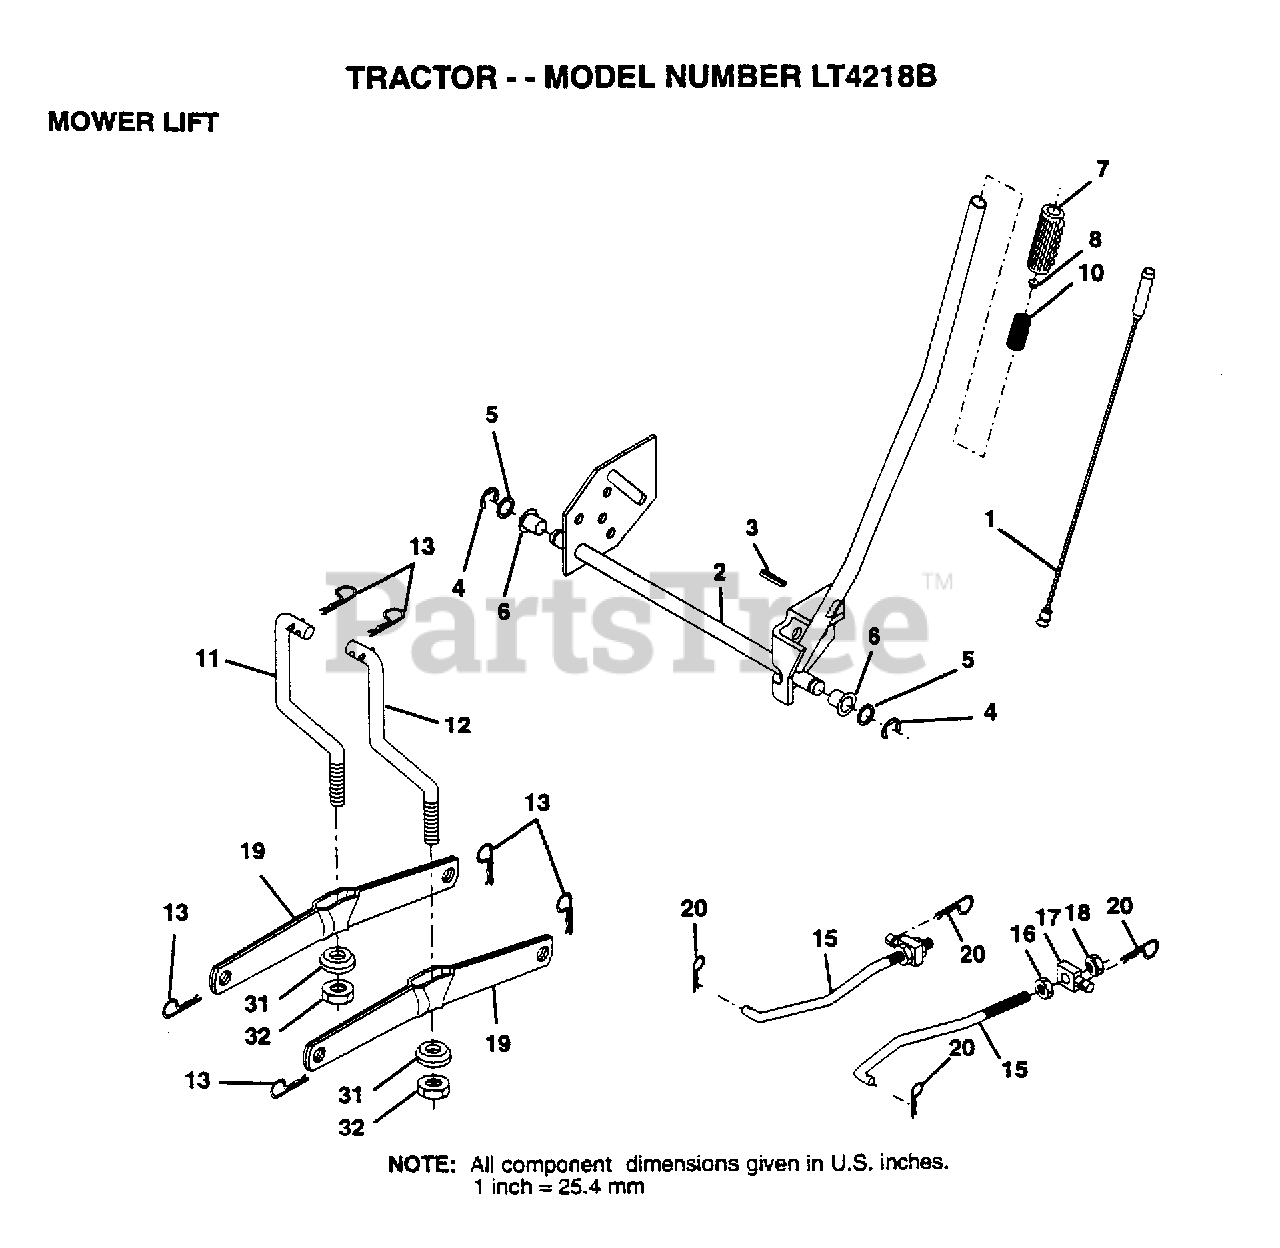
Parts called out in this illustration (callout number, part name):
1	WIRE.ASM.INNER
2	SHAFT.ASM.LIFT.RH
3	PIN GROOVE
5	WASHER
6	NYLON BEARING
7	GRIP
15	LINK.FRONT
16	NUT
17	TRUNION
18	NUT.LK.W/WSH.1/2.
19	ARM SUSP REAR
20	RETAINER.SPRING
31	BEARING PVT LH
32	NUT.LOCK.3/8-24
